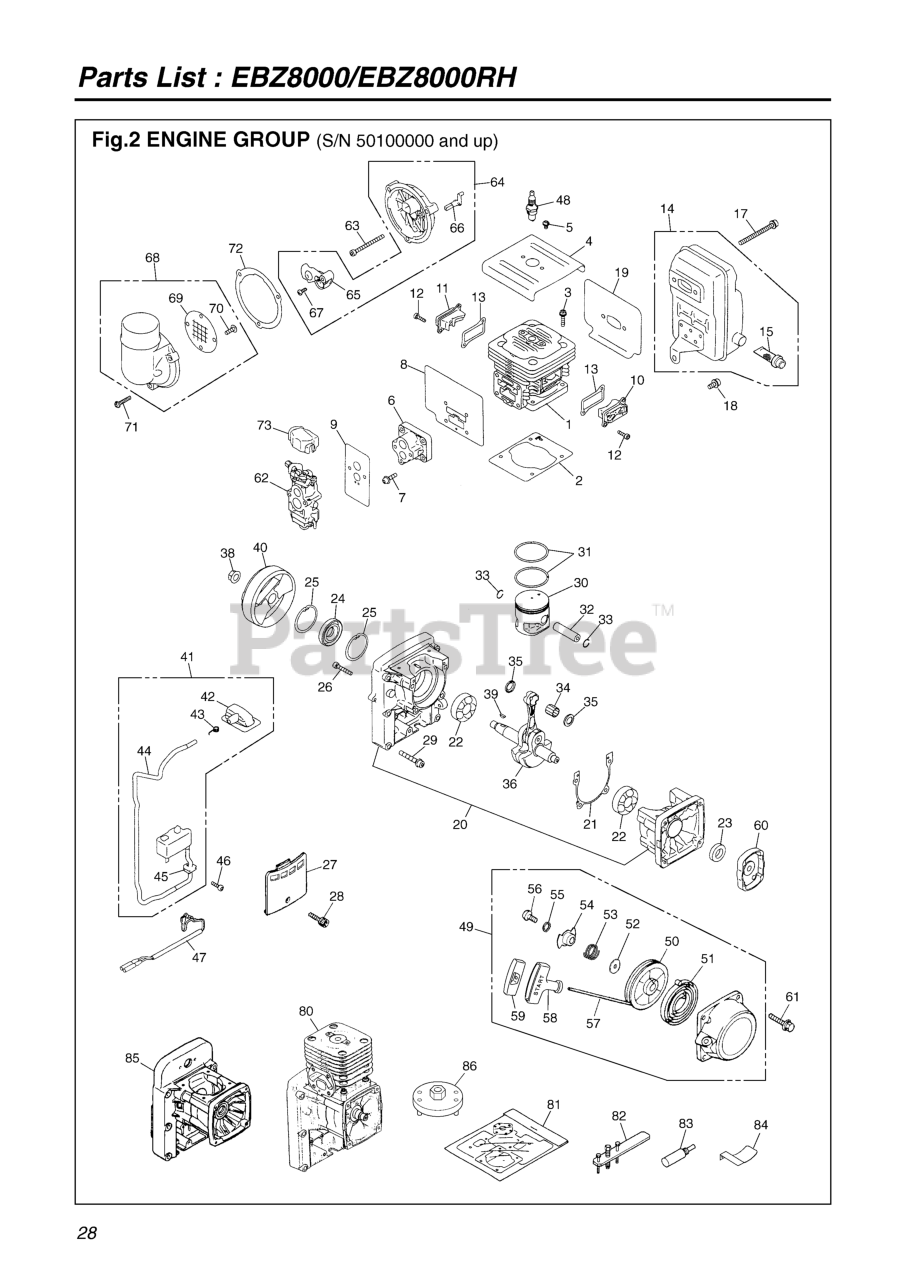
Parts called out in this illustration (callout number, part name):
2	GASKET, BASE
3	BOLT
4	PLATE, CYL
5	SCREW TORX
6	INSULATOR
7	BOLT TORX
8	GASKET, INSULATOR
9	GASKET, CARB.
10	COVER, TR-S
11	COVER,TR-F
12	BOLT TORX
13	GASKET, TR
14	MUFFLER ASSY.
15	ARRESTER
17	BOLT
18	BOLT
19	GASKET, MUFFLER (USE -15C1)
20	CRANKCASE-CASE
21	GASKET, CASE
22	BEARING
23	SEAL
24	SEAL
25	SNAP RING
26	BOLT
27	COVER
28	BOLT TORX
29	BOLT TORX
30	PISTON
31	RING
32	PIN
33	SNAP RING
34	BEARING
35	WASHER
36	CRANKSHAFT COMP
38	NUT, M10
39	KEY
40	ROTOR
41	COIL-A
42	CAP
43	SPRING
44	TUBE
45	GROMMET
46	BOLT TORX
47	CORD-C
48	SPARK PLUG
51	SPRING
56	SCREW
57	ROPE
58	KNOB
59	COVER KNOB
61	BOLT, TORX
62	CARBURETOR-A (WYA-44)
63	BOLT
66	LEVER
67	SCREW
69	SCREEN
70	SCREW
71	SCREW
72	GASKET,CUP
73	COVER
80	SHORT BLOCK (EBZ8000)
81	GASKET KIT
82	PULLER ASSY
83	STOPPER (TOOL)
85	CRANKCASE-A
86	PULLER
